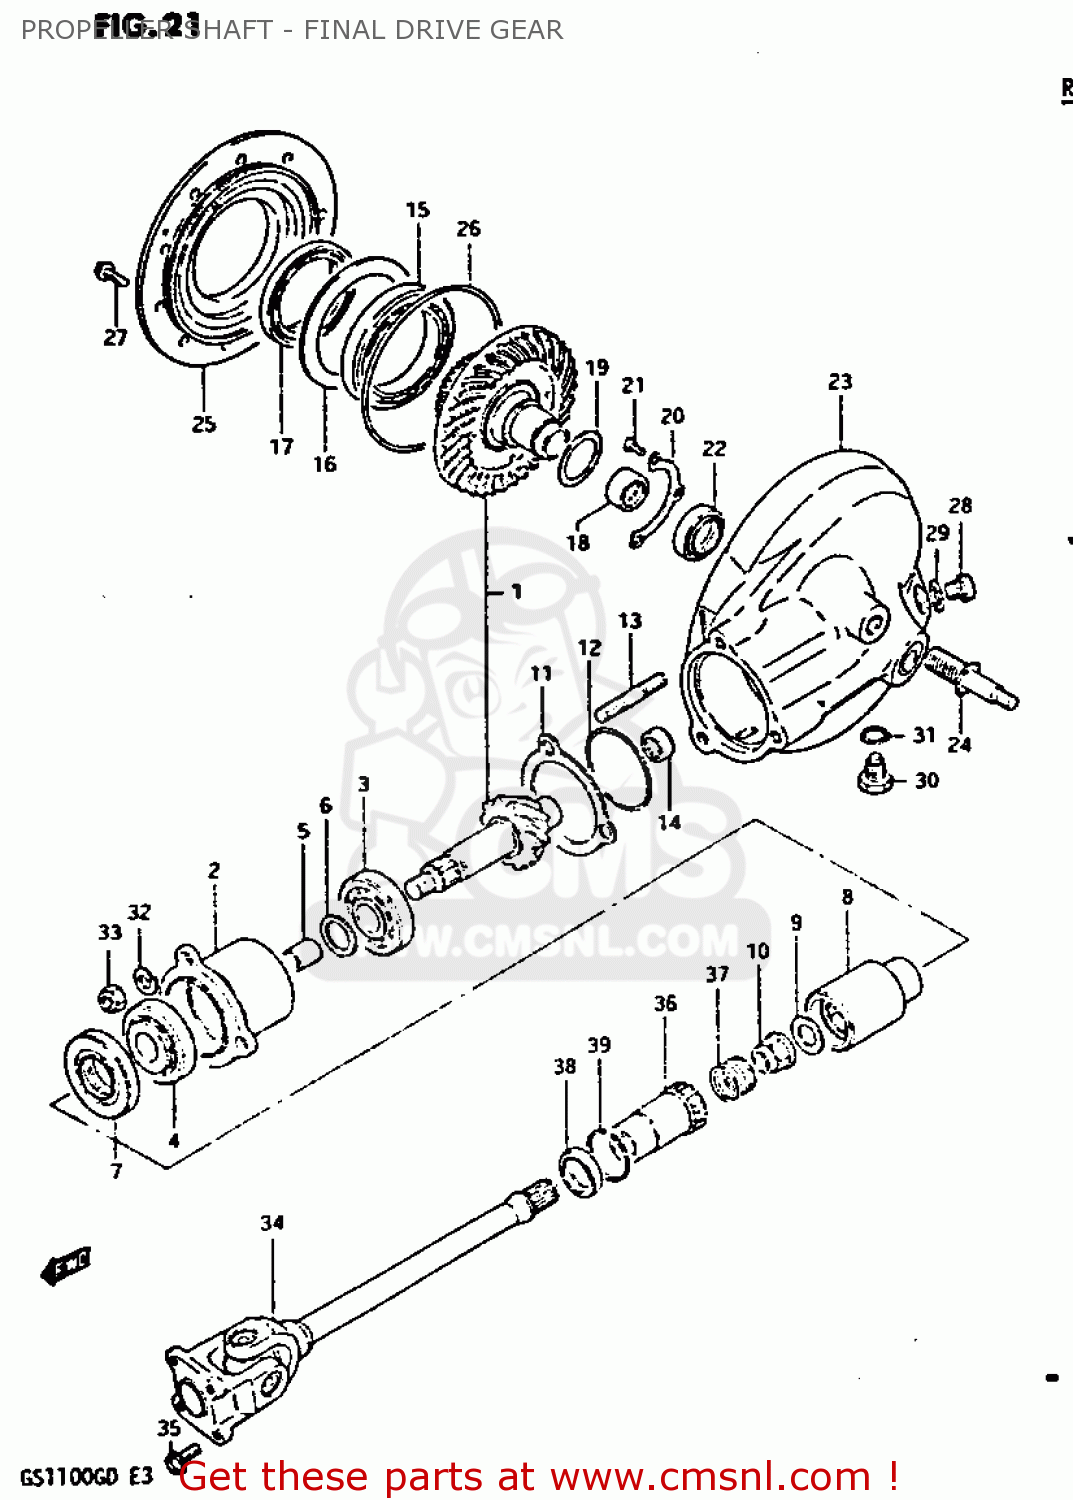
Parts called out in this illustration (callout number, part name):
1	GEAR SET,FINAL BEVEL
2	HOUSING,DRIVE GEAR
3	BEARING(25X52X19.25)
4	BEARING(25X52X16.25)
5	SPACER (25.2X30X3.5)
6	SHIM (25X30X2
7	SEAL,OIL(32X54X7)
8	GEAR,FINAL DRIVE
9	WASHER(14X29X4)
10	NUT
11	SHIM,DRIVE GEAR HOUSING
12	O RING(D:2.4,ID:62.6)
13	STUD 10X30
14	BEARING(24X33X17)
15	BEARING(70X110X13)
16	SHIM,DRIVEN GEAR BEARING
17	SEAL,OIL(70X96X16)
18	BEARING(35X48X23.7)
19	SHIM,FINAL DRIVEN GEAR
20	RETAINER,FINAL DRIVEN GEAR BRG
21	SCREW 6X12
22	SEAL,OIL(30X42X7)
23	CASE ASSEMBLY,FINAL GEAR
24	STUD
25	CASE,FINAL GEAR BEARING
26	O-RING (D:3.1 ID:144.4)
27	BOLT
28	PLUG(14X12)
29	GASKET(14X19.2X2) (NAS)
30	PLUG
31	GASKET(14X19.2X2) (NAS)
32	LOCK WASHER
33	NUT
34	SHAFT ASSEMBLY,PROPELLER
35	BOLT(8X17)
36	COUPLING,PROPELLER SHAFT
37	SPRING
38	SEAL,OIL(30X40.5X5.5)
39	CIRCLIP
